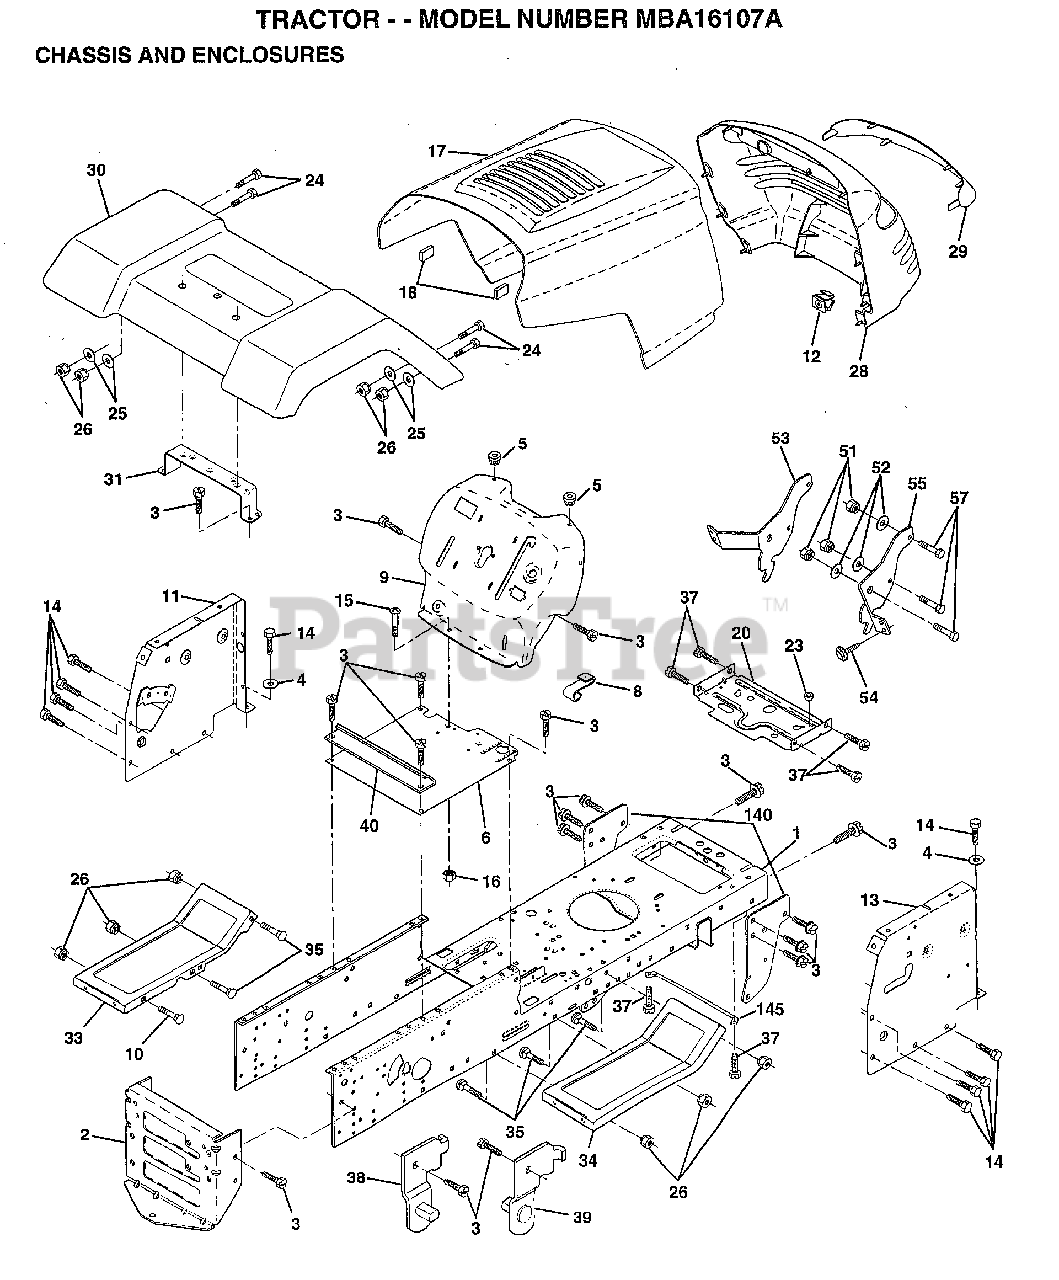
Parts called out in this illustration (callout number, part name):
1	CHASSIS.STAMPING
3	SCREW
4	WASHER
5	BUMPER-HOOD/DASH
6	SADDLE
8	CLIP.RETAINER
9	DASH SILKSCREEN
11	"PANEL-DASH,LH"
12	CLIP.TINNERMAN
14	SCREW LT
15	SCREW
17	HOOD.PNT.W/TRIM
20	"PLATE-MTG,BATT/FU"
24	BOLT
25	WASHER
26	NUT
28	GRILLE
29	LENS.GRILLE
31	BRACKET SUPT FEND
33	FOOTREST.LH.YT/GT
34	FOOTREST.RH.LT/YT
35	BOLT
37	SCREW LT
38	BRACKET ASM LH
39	BRACKET ASM RH
40	SPACER FENDER LT
51	NUT
52	WASHER
53	BRACKET.GRILLE.LH
54	SCREW.HEX.WS.HD
55	BRACKET.GRILLE.RH
140	BRKT SUSPENSION
145	"ROD POVOT,CHASSIS"
